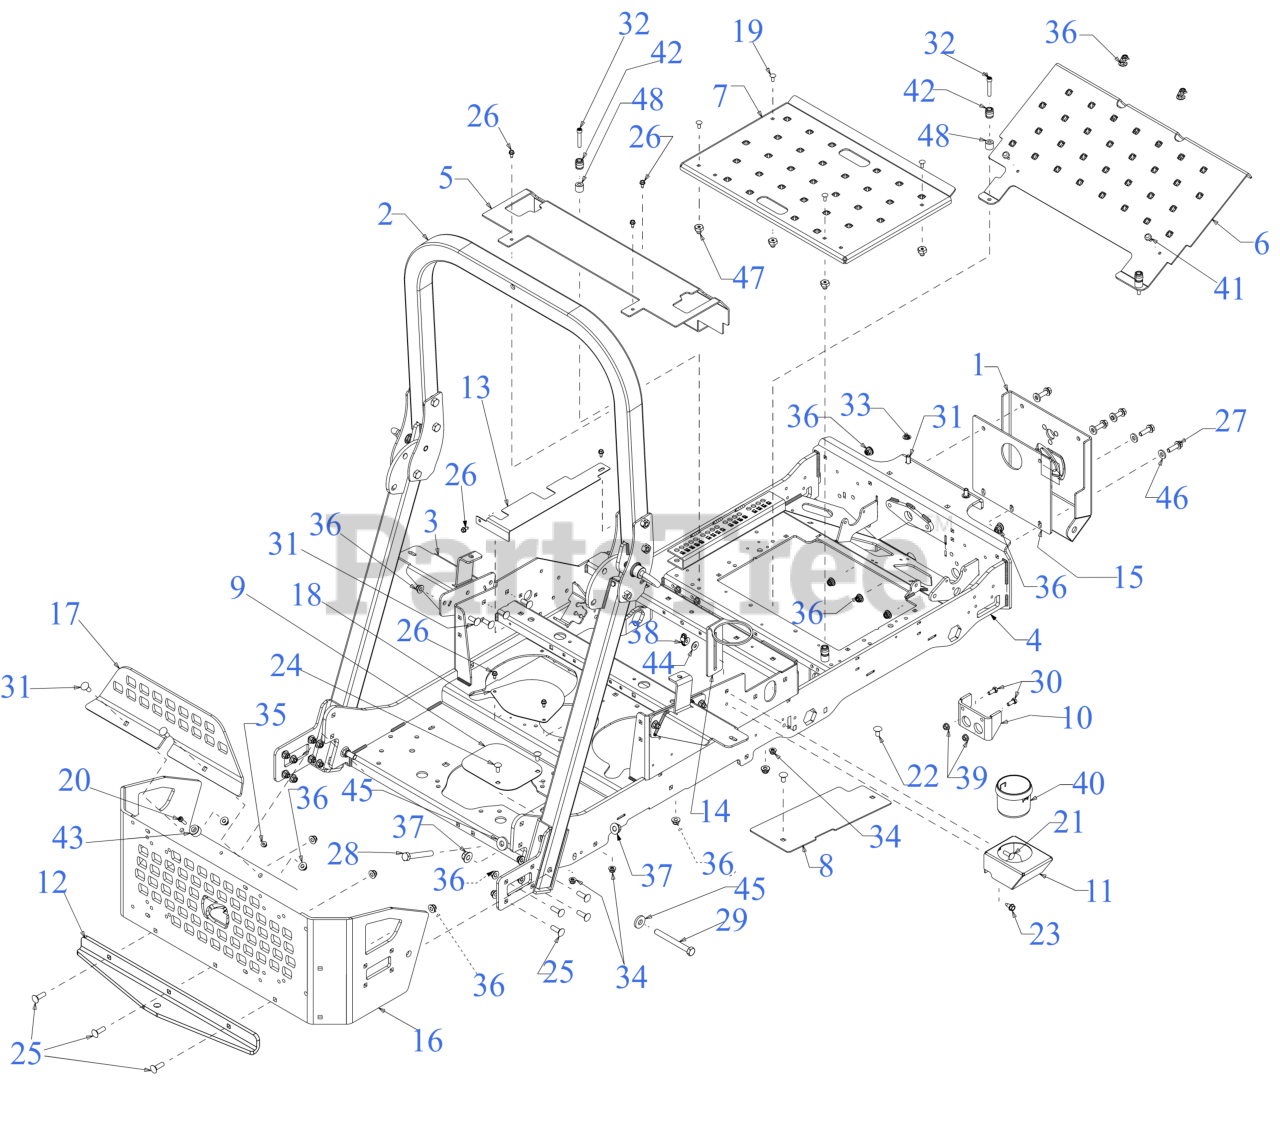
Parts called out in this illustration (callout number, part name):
2	PRO Z ROPS KIT
3	FUEL TANK MOUNT
4	FRAME
10	FRONT DECK LIFT MOUNTING BRACKET
11	LOWER CUP HOLDER
15	FRONT MOUNTING PLATE SPACER
16	BUMPER (REAR)
17	BUMPER (UPPER RR)
18	FRAME COVER PLATE
19	CARRIAGE BOLT 1/4-20 x .62
20	MACHINE SCREW 1/4-20:1
21	CARRIAGE BOLT 5/16-18 x 1.00
22	CARRIAGE BOLT 3/8-16 x .750 GR5
23	SCREW 5/16-18 x .750
24	CARRIAGE BOLT 5/16-18 x .75
25	CARRIAGE BOLT 3/8-16 X1.25 GR5
26	SCREW 1/4-20 X.500
27	SCREW 3/8-16 x 1.25 GR5
28	HEX SCREW 1/2-13 x 3.50
29	SCREW 1/2-13 x 4.5 GR 5
30	SCREW 5/16-18 x .75 GR5
31	CARRIAGE BOLT 3/8-16 x 1.00 GR5
32	SCREW 5/16-18X1.75 GR5
34	FLANGE LOCK NUT 5/16-18
35	FLANGE LOCK NUT
38	WING NUT 5/16-18
39	HEX FLANGE NUT
41	BUMPER, .62 DIA x .3
42	RADIAL BUMPER
44	FLAT WASHER
45	FLAT WASHER .531 x 1.25 x .181
46	FLAT WASHER
47	SHOULDER SPACER
